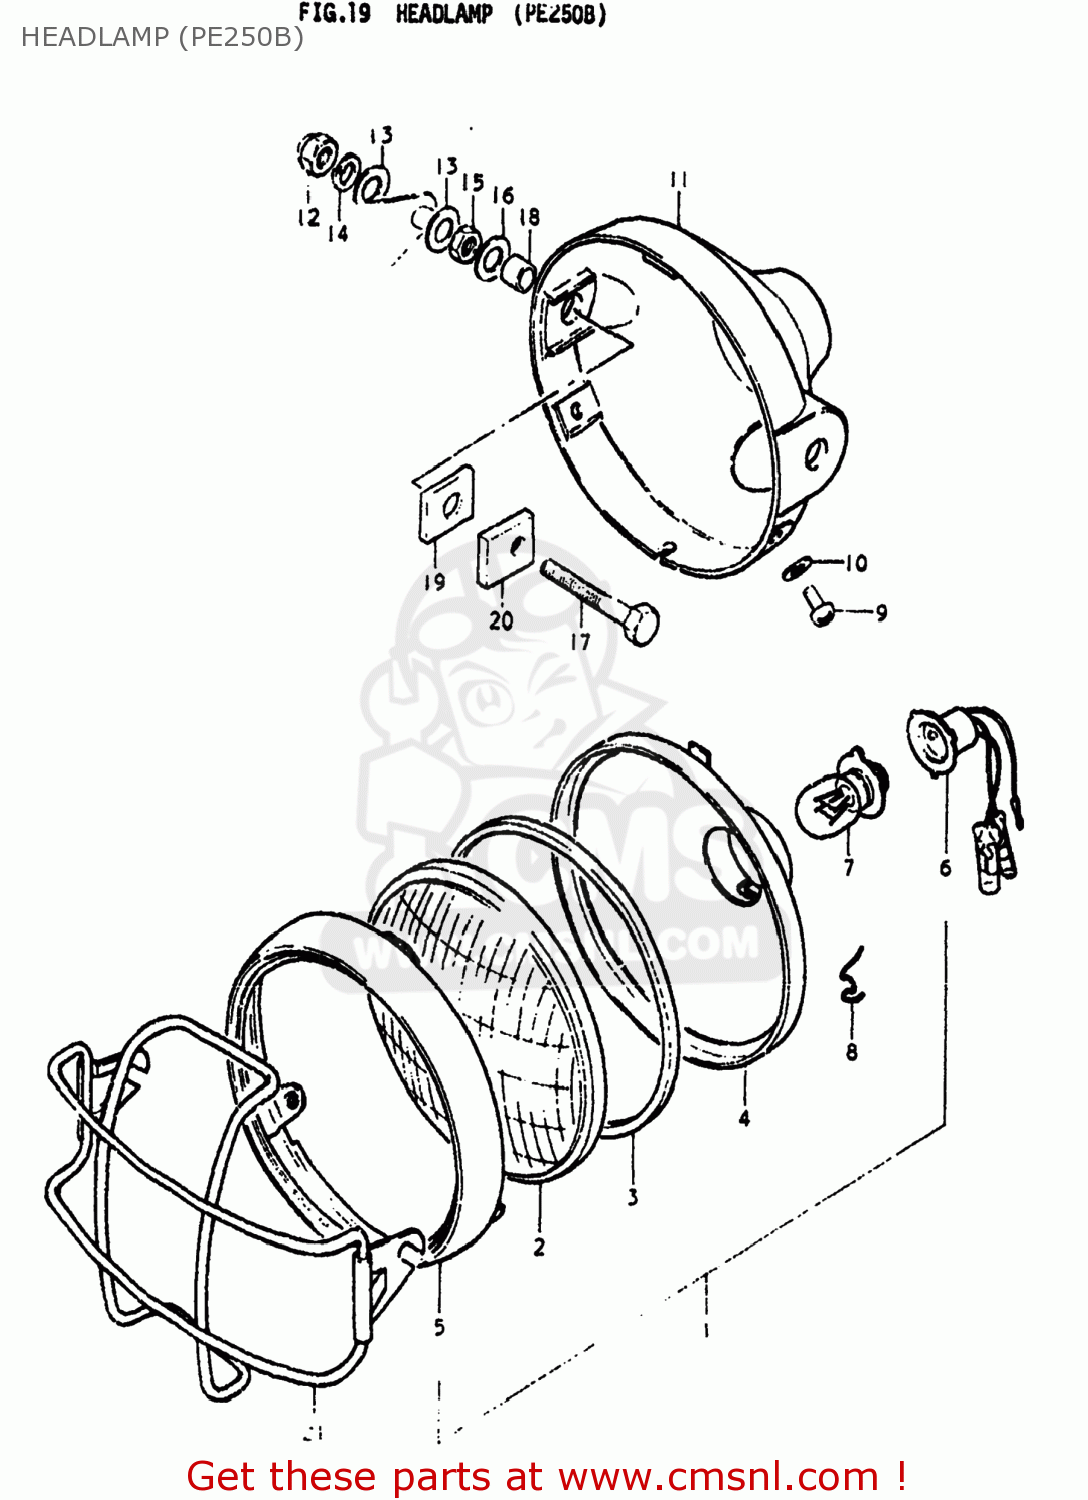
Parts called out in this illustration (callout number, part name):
1	LAMP ASSEMBLY,HEAD
2	LENS
3	GASKET (NAS)
4	REFLECTOR,HEADLAMP
5	RIM,HEADLAMP
6	SOCKET,HEADLAMP
7	BULB(6V15/15W/STANLEY,A3598HA)
8	SPRING
9	SCREW
10	WASHER
11	HOUSING,HEADLAMP
12	NUT
13	WASHER
14	NUT
15	NUT
16	WASHER
17	BOLT
18	SPACER (8.8X12X7)
19	CUSHION
20	STAY,HEADLAMP HOUSING
21	GUARD,HEADLAMP
